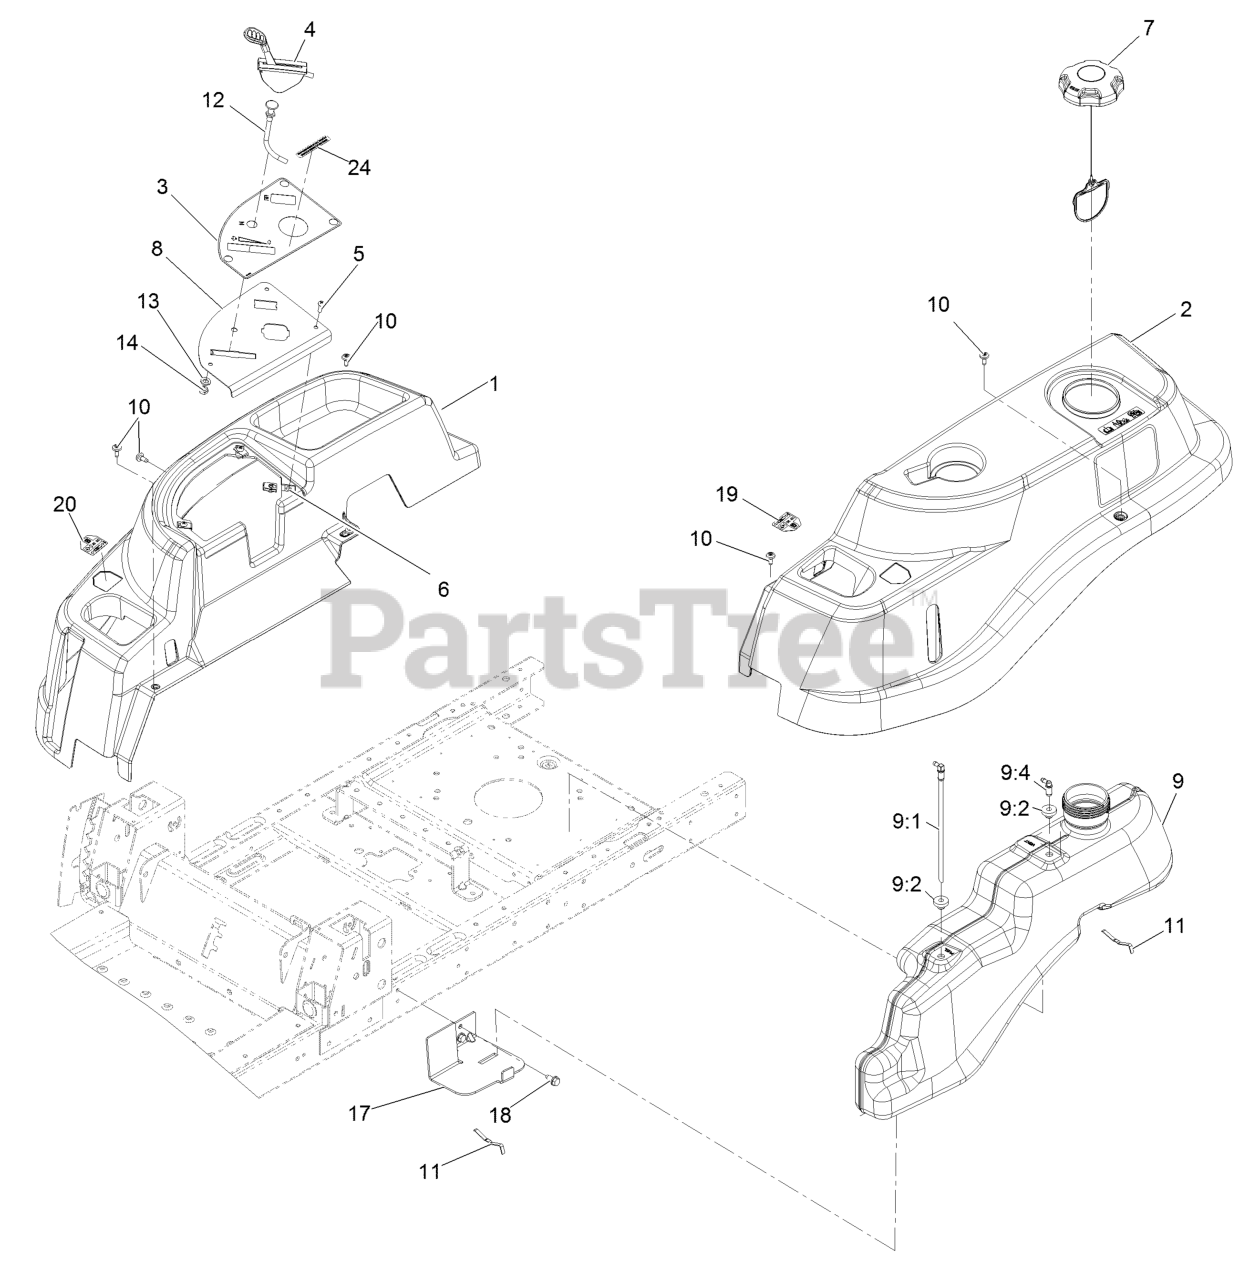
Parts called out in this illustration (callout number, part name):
3	DECAL-PANEL, CONTROL
4	CABLE-THROTTLE
5	SCREW-PRH
6	Nut-Retainer-Panel 1/4-20
8	PLATE-CONTROL
9	FUEL TANK ASM
9:1	CONNECTOR-ELBOW, 90 DEG
9:2	BUSHING
9:4	FITTING-PLASTIC
10	SCREW-SHOULDER
11	SPRING
12	CABLE-CHOKE
13	WASHER-LOCK
14	NUT-HJ
17	SUPPORT-TANK, FRONT
18	Screw-HWH 5/16-18 X 3/4 Tf
19	DECAL-LEVER, CONTROL (LH)
20	DECAL-LEVER, CONTROL (RH)
24	DECAL-SHUTDOWN
